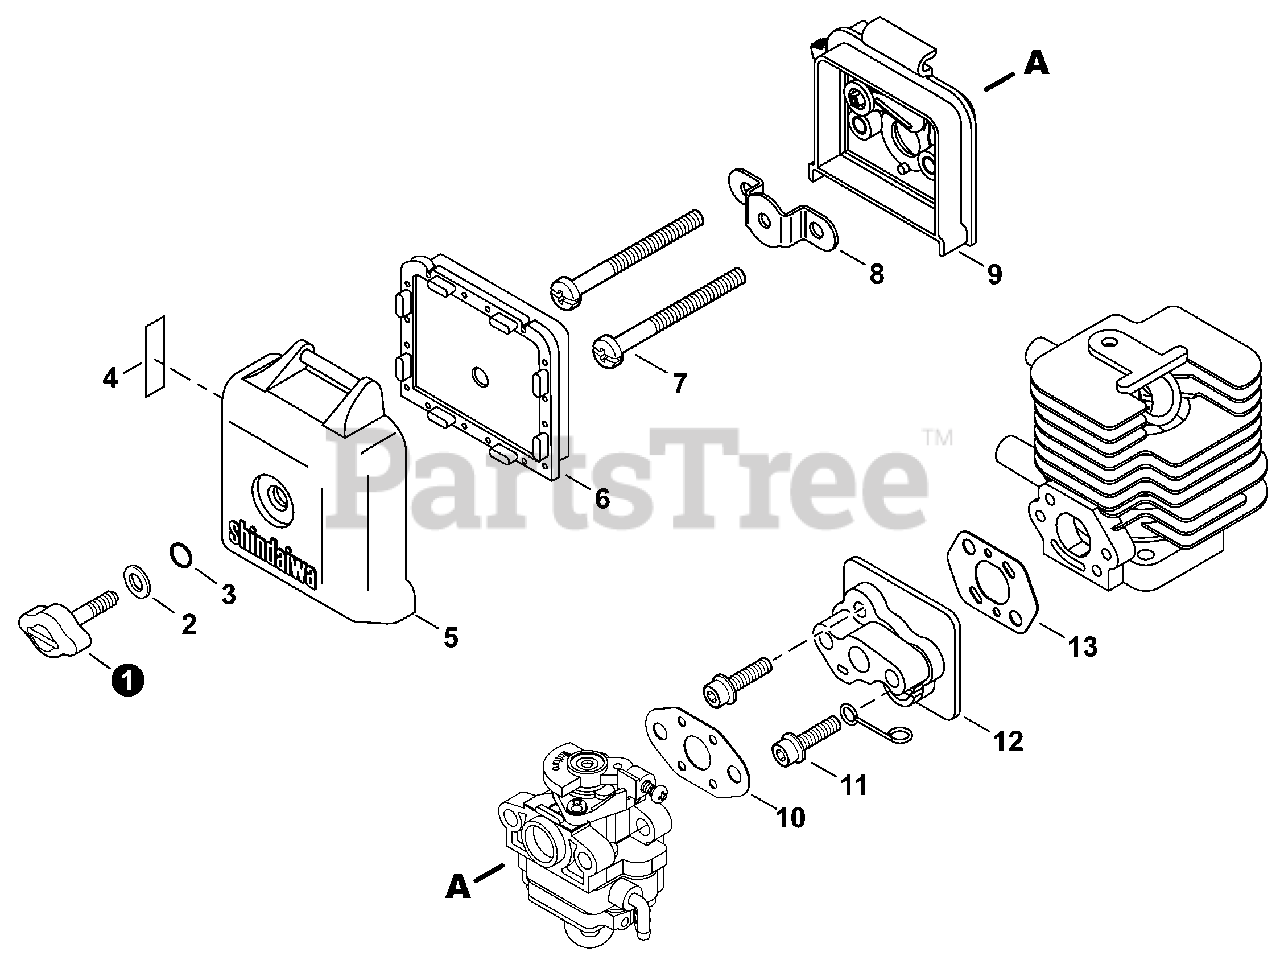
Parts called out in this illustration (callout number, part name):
1	THUMBSCREW
2	WASHER, CONE M6
4	LABEL, CHOKE
5	COVER, AIR FILTER
6	FILTER, AIR
7	SCREW M5×60
8	BRACKET
9	CASE, AIR FILTER
10	GASKET, CARBURETOR
11	BOLT M5×30
12	INSULATOR, INTAKE
13	GASKET, INTAKE
